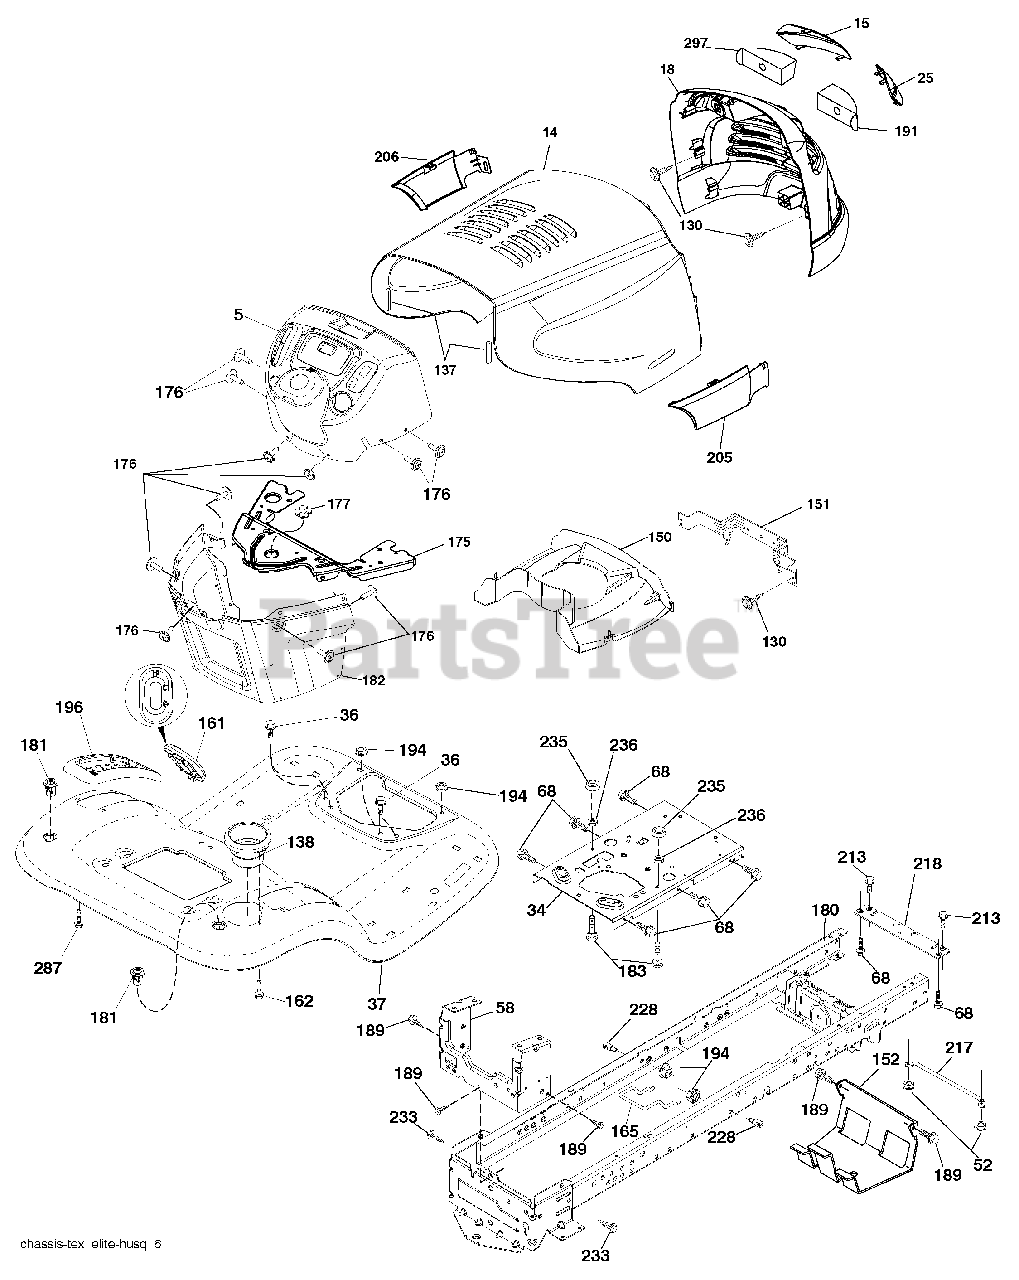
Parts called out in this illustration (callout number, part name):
14	Hood
15	Lens Grille LH
18	Grille
25	Lens Grille RH
34	Plate Engine
36	Screw 5/16-18 x 3/4
52	Nut Crown Lock 5/16-18
58	Drawbar Upper
68	Screw THDROL 5/16-18 x 1/2
130	Screw #10 x 0.750 BOS Thread
137	Bumper Hood
138	Cupholder
150	Duct Heat Hood
151	Bracket Pivot
152	Shield Browning/Debris
159	Screw 3/8-16 x 3/4
161	Window Fuel
162	Screw Hex Wsh Hi-Lo 1/4 x 1/2 unc
165	Support Tank Rear
175	Crossmember
176	Screw 10-24 x 5/8 Wshd Qdrx
177	Bushing Steering
180	Chassis
181	Bushing Mtg. Fender Crgo.
182	Dash Lower
183	Bolt Full Thd. 5/16-18 x 1-1/4
189	Screw 5/16-18 x 3/4
191	Insert Lens Reflective RH
194	Nut Lock Hex Flange 5/16-18
196	Console Asm. Deck Lift
213	Bolt Hex HD 5/16-18 unc x 3/4
217	Rod Pivot
218	X-Piece Hood
228	Stud Fastener
233	Bolt Shoulder
235	Spacer Fender
236	Nut Center Lock 5/16-18 unc
287	Screw Hex Washead 1/4-20 x 3/8
297	Insert Lens Reflective LH
297	Kit Bumper
